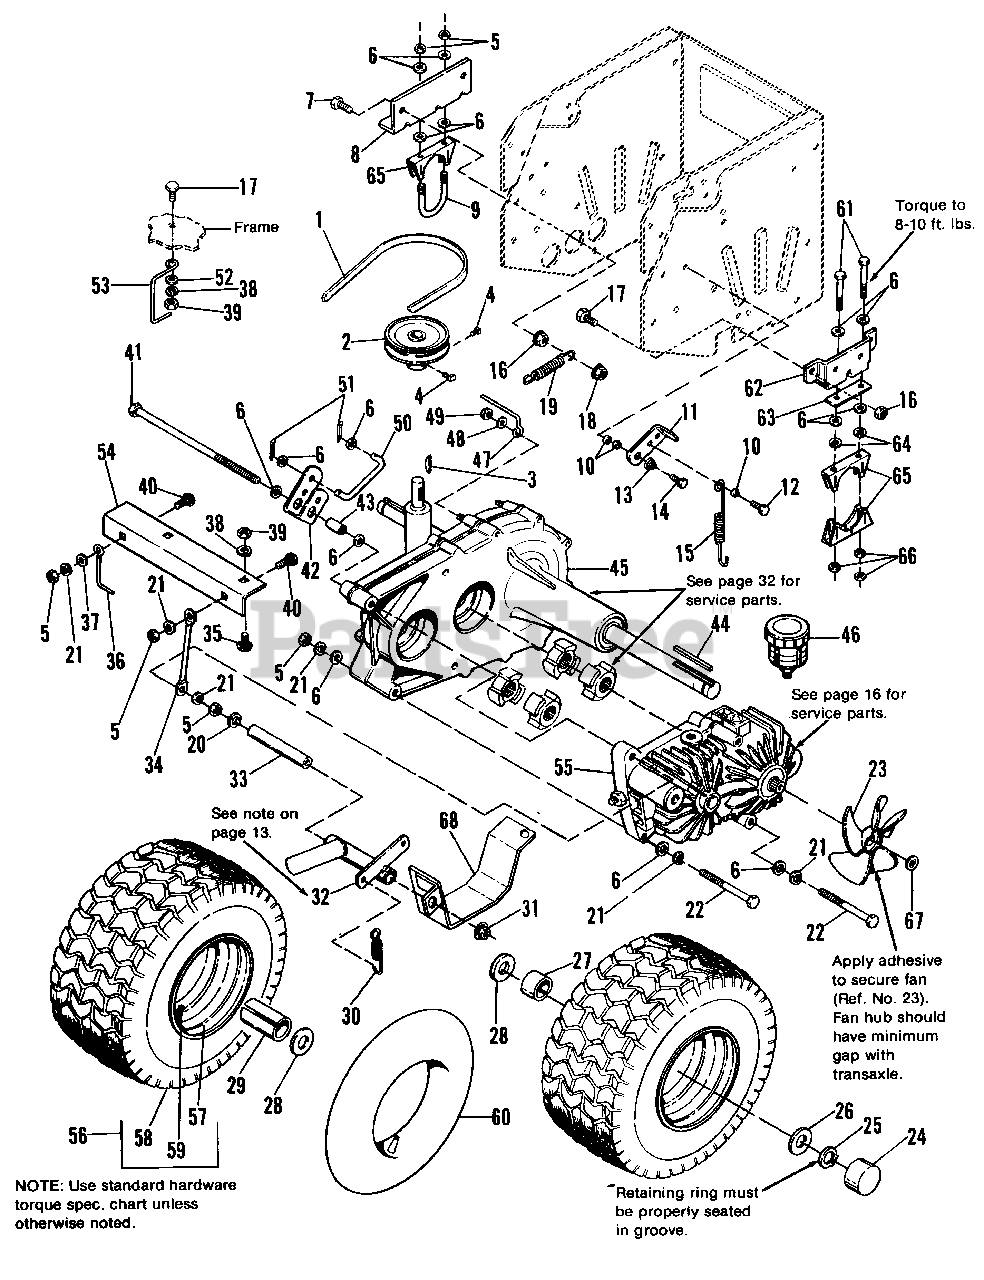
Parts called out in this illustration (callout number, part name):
2	PULLEY ASSY.
3	KEY, Hi-Pro, 1/8 x 5/8, #5
4	SET SCREW, Sq. Hd., 1/4-28
5	NUT, Hex, 5/16-18
6	WASHER, 5/16 Std.
7	CAPSCREW, Hex Hd., 3/8-16 x 1-1/2
8	SUPPORT, Transmission
11	LEVER, Hydro Release Valve
12	SCREW, Taptite, 1/4-20 x 1/2
13	SPRING, Conical
14	SCREW, Taptite, 1/4-20 x 3/4
15	SPRING, Tension
16	NUT, Hex Flange Lock, 3/8-16
17	CAPSCREW, Hex, 3/8-16 x 1
18	NUT, Hex Flange, Two-Way Lock, 3/8-16
19	SPRING
20	WASHER, 11/32
21	LOCKWASHER, 5/16
22	CAPSCREW, Hex Hd., 5/16-18 x 4-1/2
23	FAN, Blade, 5"
24	CAP, Hub, Threaded
26	WASHER, 3/4
28	WASHER
31	NUT, Hex, Flange, Two-Way Lock, 5/16-18
32	TOW VALVE LEVER ASSY.
33	TUBE, Pivot, Internal
34	TORQUE STRAP
35	CARRIAGE BOLT, 3/8-16 x 7/8
36	STOP, Belt
37	WASHER, Plain, 5/16
38	LOCKWASHER, 3/8
39	NUT, Hex, 3/8-16
40	CARRIAGE BOLT, 5/16-18 x 1
41	CAPSCREW, Hex Hd., 5/16-18 x 11
42	PIVOT, Brake
44	KEY, 3/16 x 3/16 x 1-1/2
46	RESERVOIR, Expansion
47	BELT GUIDE
48	WASHER
49	NUT, Hex, Flange, Two-Way Lock, 1/4-20
50	ROD, Brake
51	PIN, Cotter
52	WASHER, 3/8
54	BRACKET, Support
55	TRANSMISSION, Hydro
56	WHEEL & TIRE ASSY., 18 x 8.50-8
57	WHEEL ASSY.
58	TIRE, Turf Saver, 18 x 8.50-8
59	VALVE STEM & CAP
61	CAPSCREW, Hex Hd., 5/16-18 x 3-1/2
62	BRACKET, Transmission Support
63	PLATE, Shim
64	NUT, Push
65	CLAMP, "U" Bracket
66	NUT, Esna, Hex Lk., 5/16-18
67	RING, Self-Locking
68	GUARD, Fan
